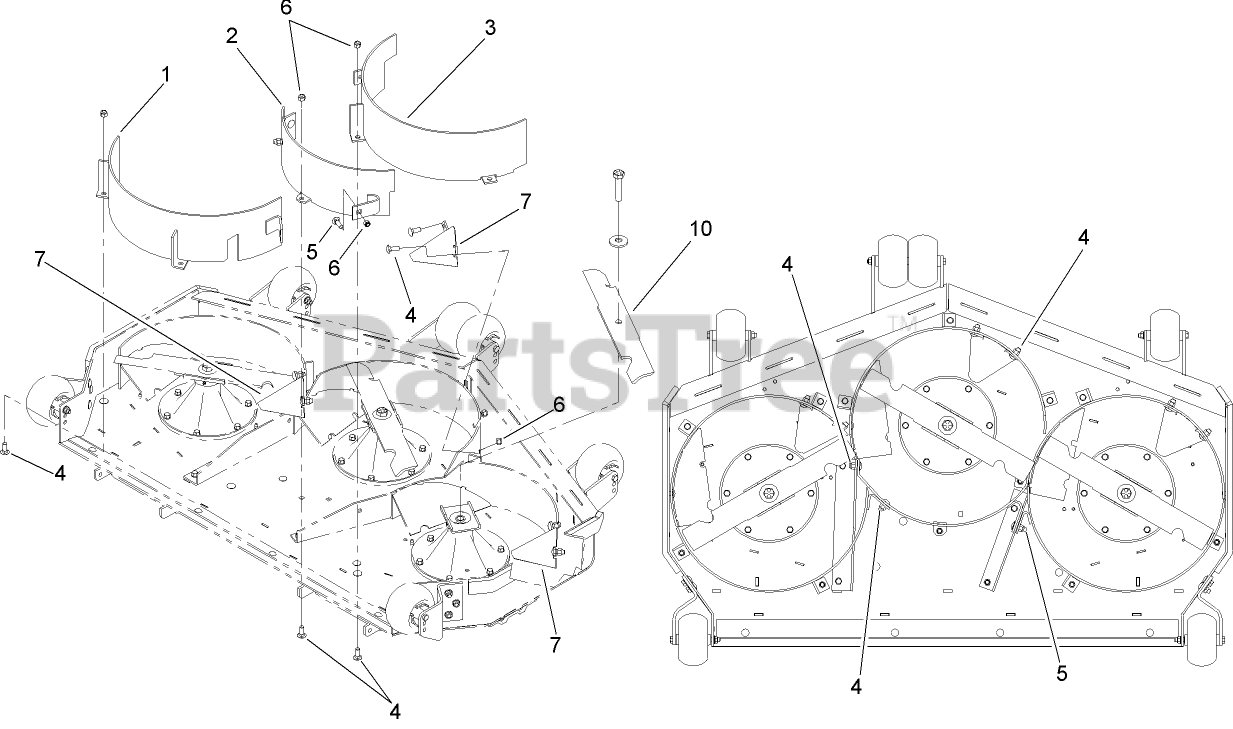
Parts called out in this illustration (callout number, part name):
1	RH BAFFLE ASM
2	CENTER BAFFLE ASM
3	LH BAFFLE ASM
4	BOLT-CARR
5	BOLT-CARR
6	NUT-LOCK, NI
10	BLADE-RECYCLER
